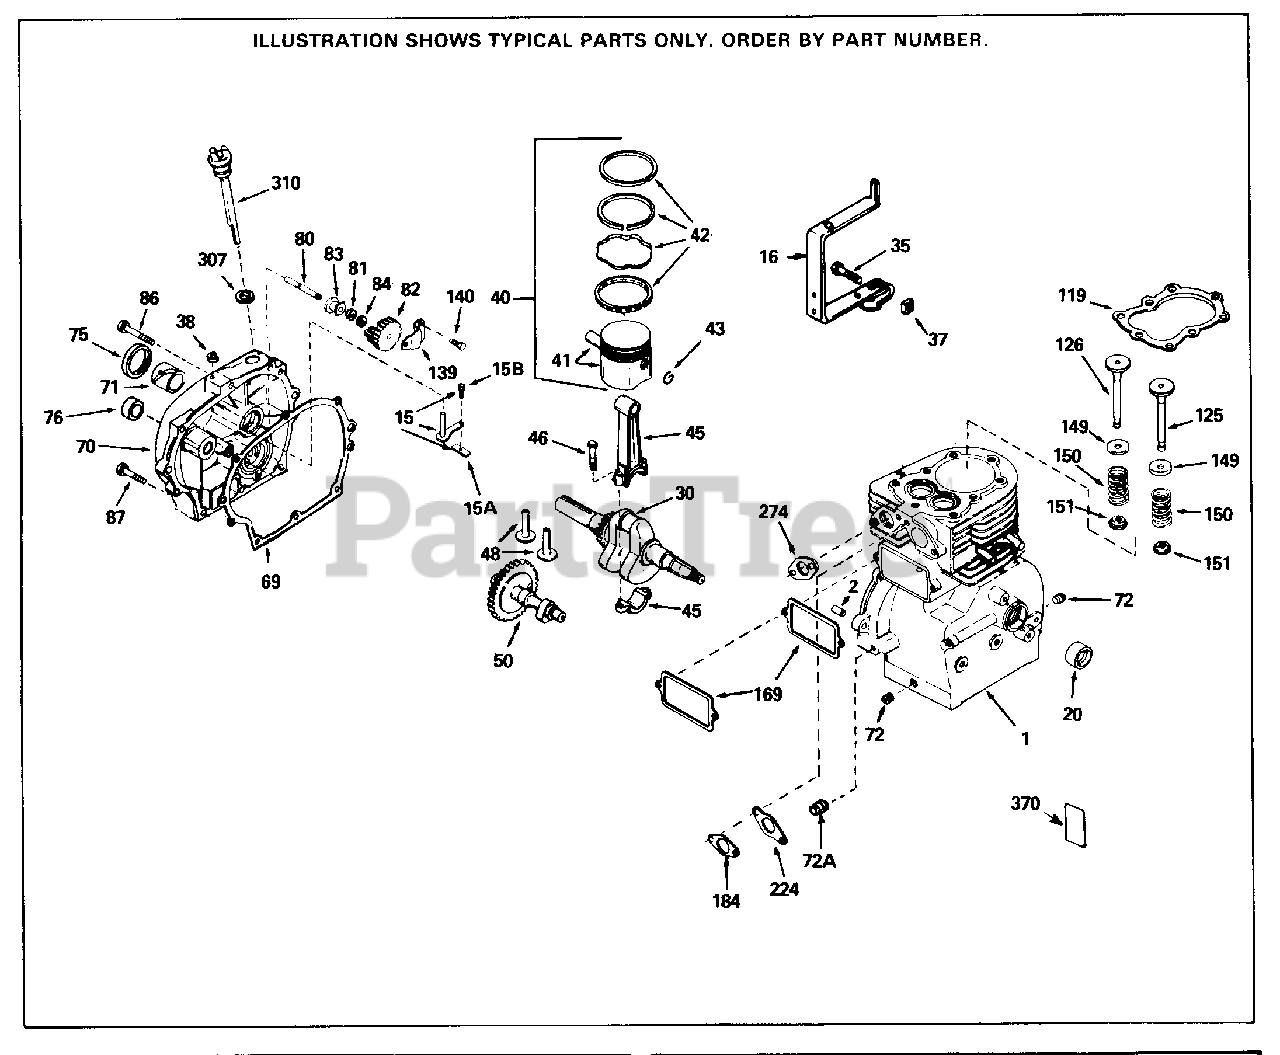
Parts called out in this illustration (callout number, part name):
1	"Cylinder (Incl. 2, 20, 72 & 72A)
2	Dowel Pin
15	Governor Rod (Incl. 15A & 15B)
15A	Governor Yoke
15B	Screw, 6-40 x 5/16"
16	Governor Lever
16A	Governor Bracket
18	Screw, Torx T-15, 8-32 x 19/64"
20	Oil Seal
35	Screw, 10-32 x 3/4"
36	Lock Washer #8
37	Lock Nut, 10-32
38	Retaining Ring
40	Piston, Pin & Ring Set (Std.)
40	Piston, Pin & Ring Set (.010" OS)
40	Piston, Pin & Ring Set (.020" OS)
41	Piston & Pin Ass'y. (Std.) (Incl. 43)
41	Piston & Pin Ass'y. (.010" OS) Incl. 43
41	Piston & Pin Ass'y. (.020" OS) Incl. 43
42	Ring Set (Std.)
42	Ring Set (.010" OS)
42	Ring SEt (.020" OS)
43	Piston Pin Retaining Ring
45	Connecting Rod Ass'y. (Incl. 46 & 49)
46	Connecting Rod Bolt
48	Valve Lifter
49	Oil Dipper
50	Camshaft (MCR)
69	* Cylinder Cover Gasket
70	Cylinder Cover Incl. 71,75,76,80 & 31 1
71	Crankshaft Bushing
72	Oil Drain Plug (Sq. hd., 1/4-18)
72A	Oil Drain Plug
75	Oil Seal
76	Camshaft Seal
80	Governor Shaft
82	Governor Gear Ass'y. (Incl. 81)
83	Governor Spool
84	Retaining Ring
86	Screw, 1/4-20 x 1-1/4"
87	Screw, 1/4-20 x 1-3/4"
119	Cylinderhead Gasket
125	Exhaust Valve (Std.)(Incl. 151)
125	Exhaust Valve (1/32" OS) (Incl. 151)
126	Intake Valve (Std.) (Incl. 151)
126	Intake Valve (1/32" OS) (Incl. 151)
139	Governor Gear Bracket
140	Screw, Torx T-25, 10-24 x 1/2"
149	Valve Spring Cap
150	Valve Spring
151	Valve Spring Keeper
169	Valve Cover Gasket
184	Carburetor To Intake Pipe Gasket
224	Intake Pipe Gasket
305	Oil Fill Tube
310	Dipstick
370	Lubrication Decal
